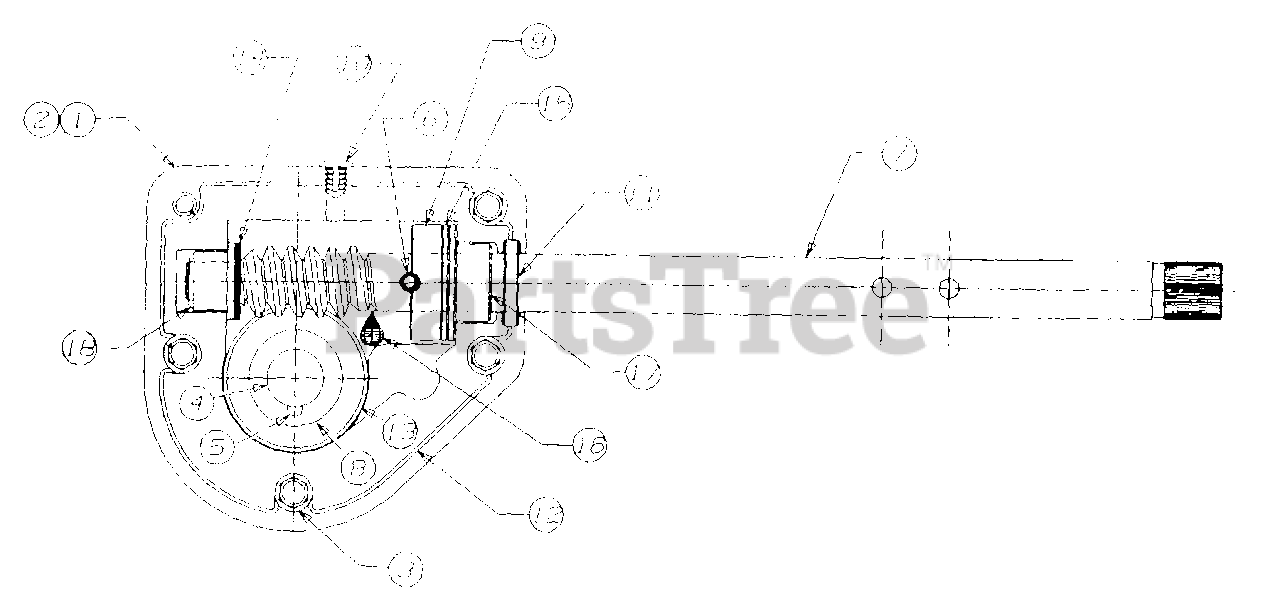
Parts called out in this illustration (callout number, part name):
1	Housing - L.H.
2	Housing - R.H.
3	Screw
4	Spiral Axle 28"
5	Key
6	Pin-Spiral
7	Shaft-Worm
8	Gear-Worm
9	Collar-Thrust
11	Seal-Oil
12	Locktite 5699
13	Washer-Flat
14	Washer-Flat
15	Washer-Flat
16	Grease
17	Bearing-Flange
18	Bearing-Flange
